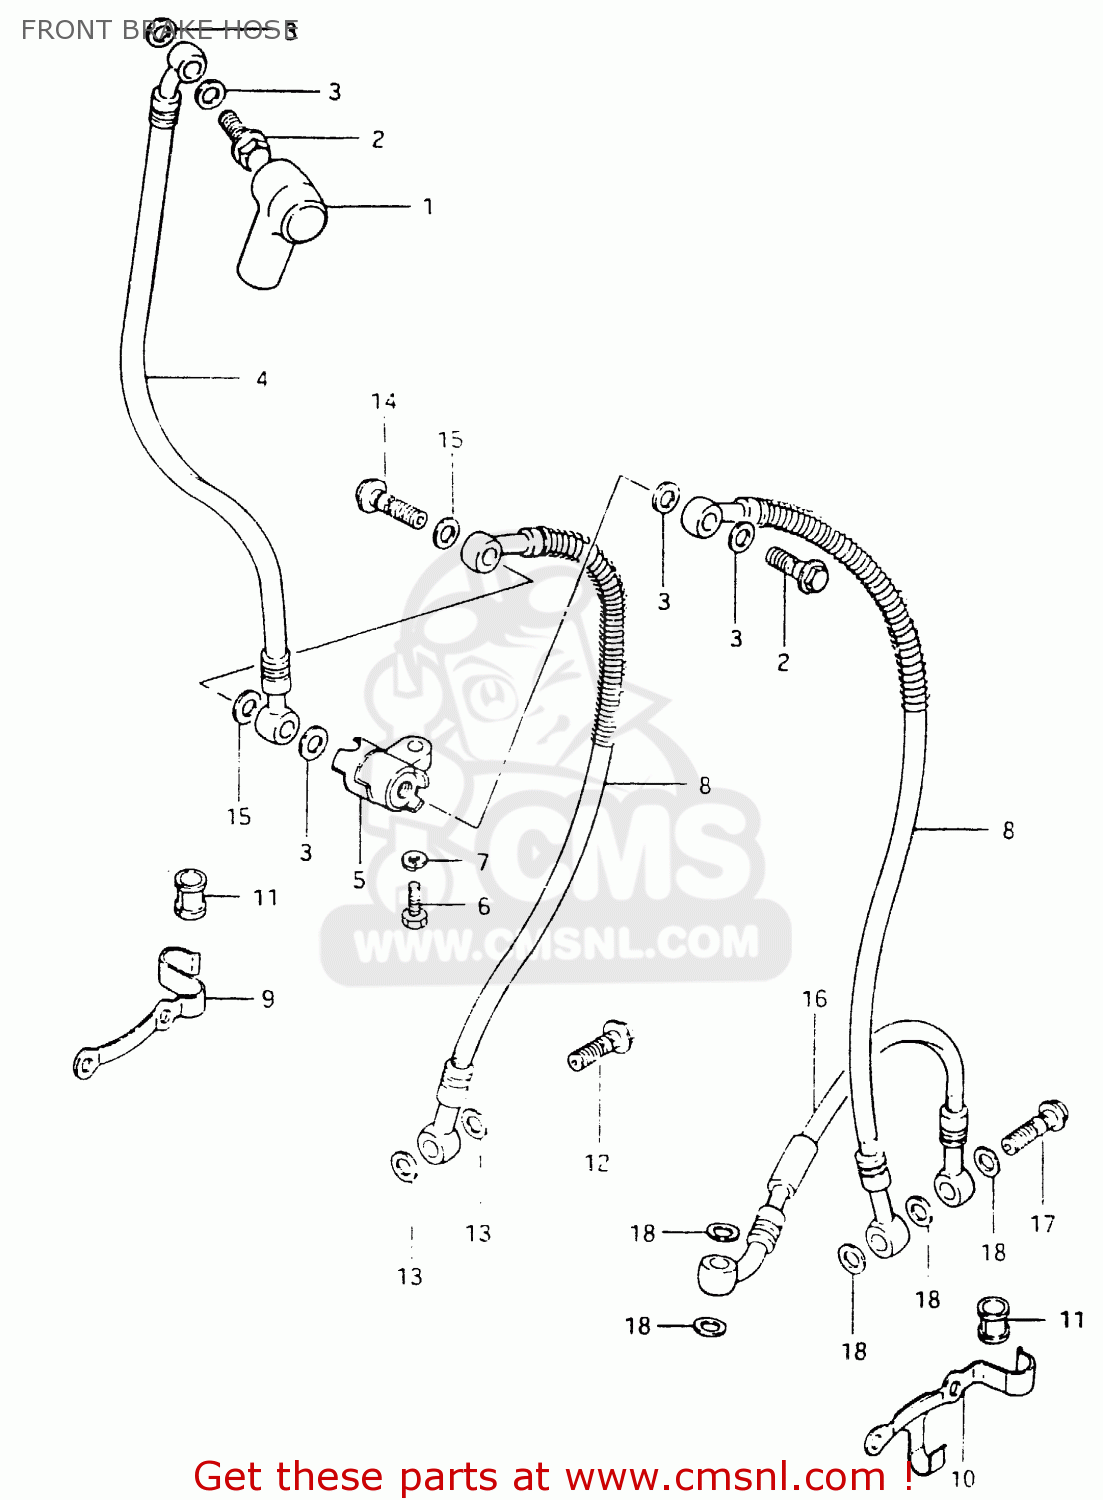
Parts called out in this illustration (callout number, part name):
1	BOOT,MASTER CYLINDER
2	BOLT UNION
3	WASHER
4	HOSE,FRONT BRAKE
5	JOINT,BRAKE HOSE
6	BOLT
7	LOCK WASHER
8	HOSE,BRAKE NO.2
9	GUIDE,BRAKE HOSE NO.2
10	CLAMP RH
11	BUSH,BRAKE HOSE GUIDE,NO.2
12	BOLT UNION
13	WASHER
14	BOLT,UNION
15	WASHER
16	HOSE, ANTINOSE DIVE
17	BOLT,UNION
18	WASHER
